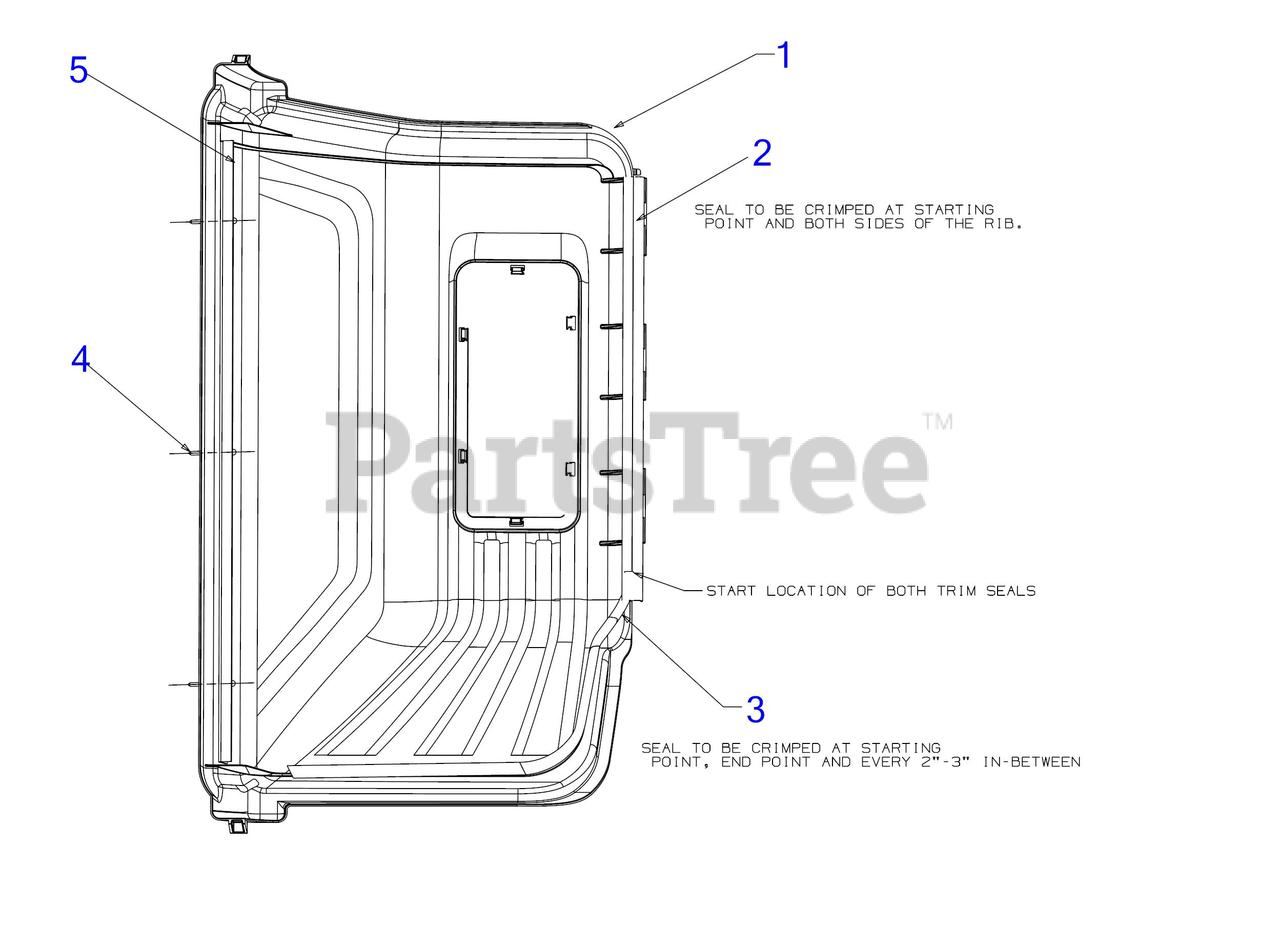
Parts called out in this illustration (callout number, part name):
1	TWIN BAGGER COVER W/ WINDOW
1	BAGGER SIGHT WINDOW
2	TRIM LOCK SEAL 17.4"
3	TRIM LOCK SEAL 21.5"
4	RIVOT
